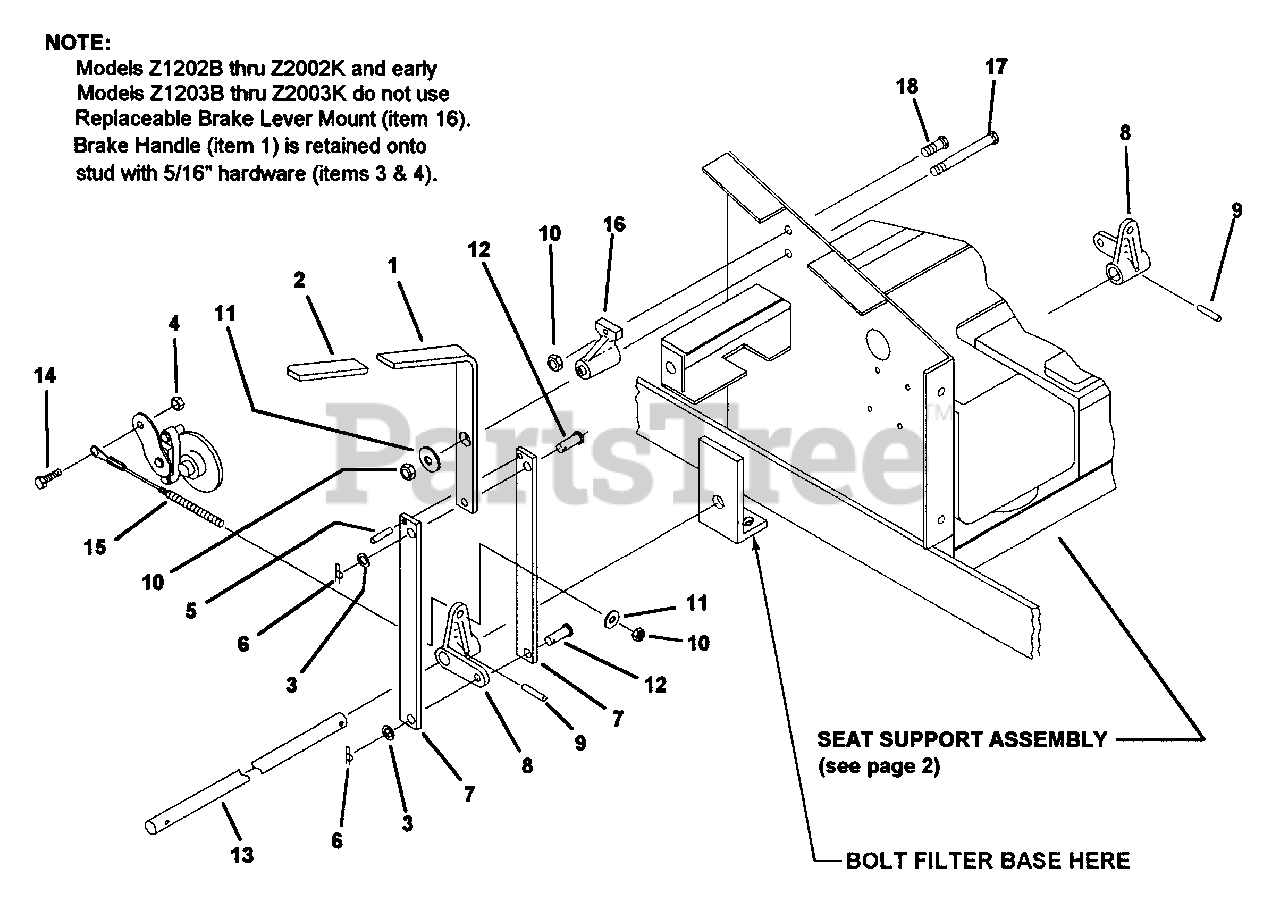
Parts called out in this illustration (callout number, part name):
1	BRAKE HANDLE
2	GRIP, HANDLE
3	WASHER, FLAT STD. 5/16"
4	NUT, 5/16-18 NYLOC
5	ROLL PIN, 3/16 X 7/8" LONG, SPIRAL
6	COTTER, RUE RING 5/16-3/8 PIN
7	HANDLE LINK
8	BRAKE ARM
9	ROLL PIN, 3/16 X 1" LONG SPIRAL
10	NUT, 1 /4-20 NYLOCK
11	WASHER, FLAT STD. 1/4"
12	CLEVIS PIN, 5/16 X 7/8" LONG
13	BRAKE ROD
14	BOLT, 5/16-18 X 3/4" GR. 5
15	CABLE ASSEMBLY, BRAKE
16	BRAKE LEVER MOUNT
17	BOLT, 1/4-20 X 3", Hex Head
18	BOLT, 1/4-20 x 1", Hex Head
